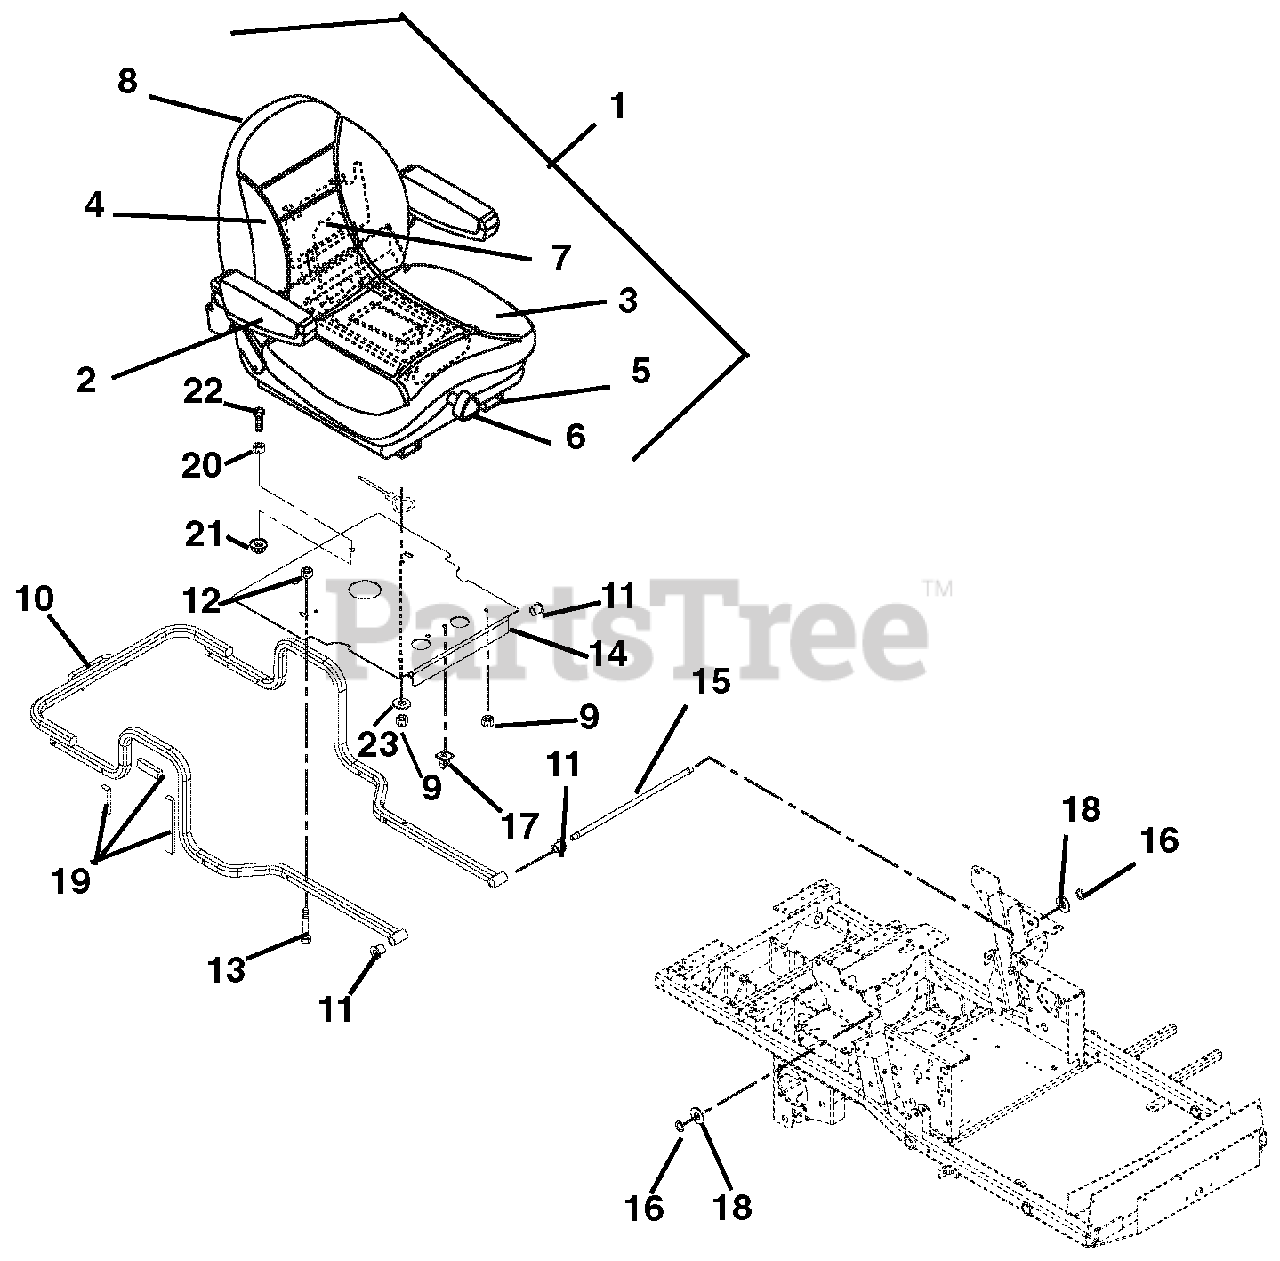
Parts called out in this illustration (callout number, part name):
1	SEAT - SUSPENSION - LIGHT GRAY
2	KIT,ARMREST PAD ONLY 1 PER KIT
3	KIT-SEAT CUSHION-LIGHT GRAY
4	KIT-BACK CUSHION-LIGHT GRAY
5	KIT-SEAT SLIDE
6	KIT-SEAT KNOB
7	KIT-SPRING AND SADDLE
8	KIT-SEAT BACK PANEL
9	@NUT-LK-TOP-FLG .31-18 YWZC
10	WMT, HOOD FRAME
11	BSHG-FLG .515X.750X.745X1.00NY
12	@NUT-LK-TOP-FLG .38-16 YWZC
13	BLT, .38-16X1.50 RIB NECK YWZC
14	WMT, SEAT PIVOT MOUNT
15	ROD - SEAT FRAME PIVOT
16	RG-RTNG-EXT .500X.050 (SNAP)
17	CLIP-.38
18	@WSHR-FL-STL.531X1.06X.095YWZC
19	VHB TAPE 4941F
20	@NUT-HEX .50-13 YWZC
21	@NUT-LK-TOP-FLG .50-13 YWZC
22	@BLT-HEX .50-13X1.50 GR5 YWZC
23	WSHR-FL-STL .344X1.125X.135
